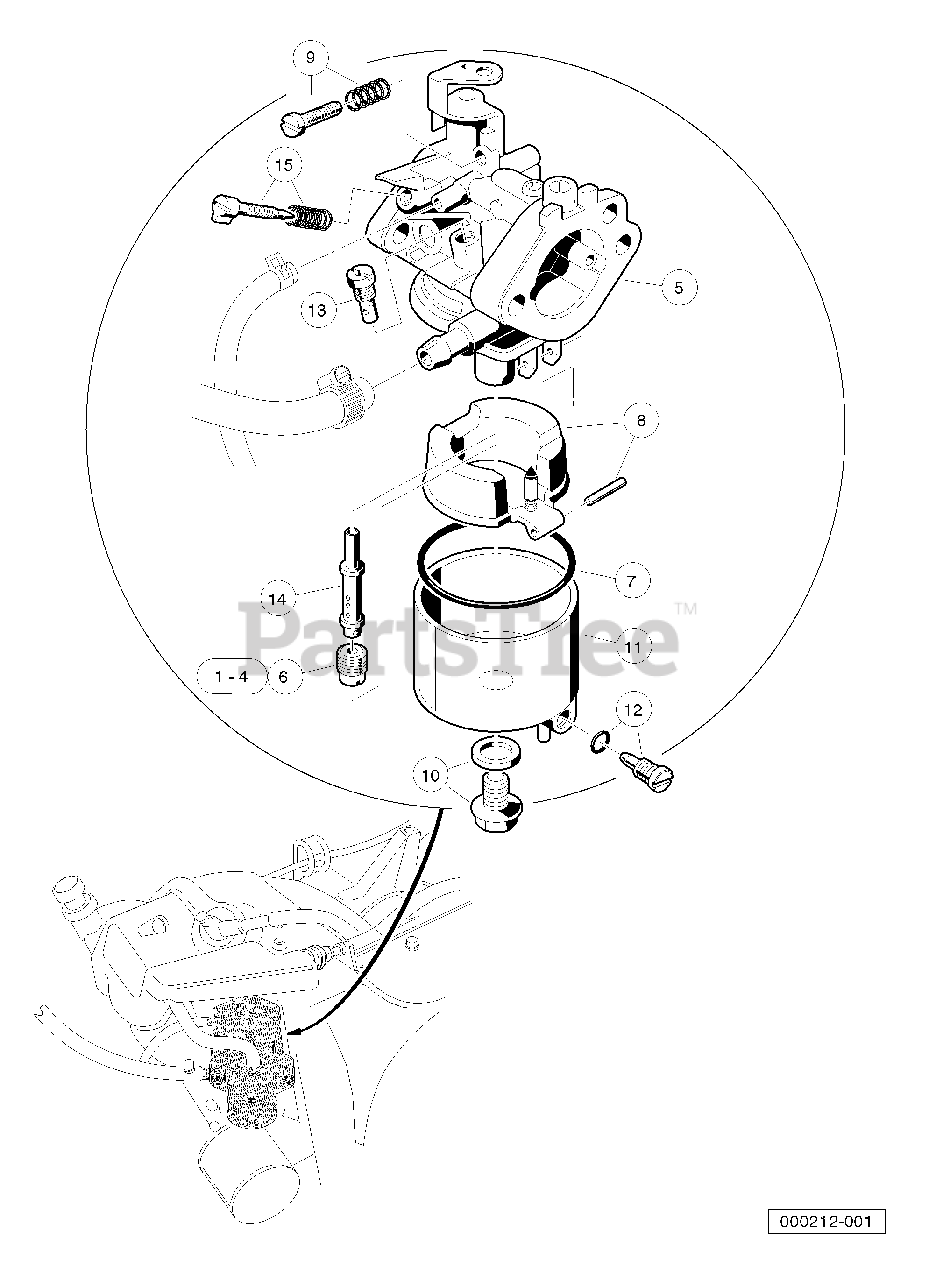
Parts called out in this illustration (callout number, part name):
1	Jet, Altitude, # 75
2	Jet, Altitude, # 78
3	Jet, Altitude, # 80
4	Jet, Altitude, # 82
5	Carburetor, FE350D
6	Jet, Altitude, # 85
7	Gasket, Carburetor Bowl OHV
8	Float Assembly
9	Screw Assembly
11	Chamber Assembly, Float
12	Screw Assembly
13	Jet, #40 Pilot
14	Nozzle, Main
15	Assembly, Pilot Air Screw
